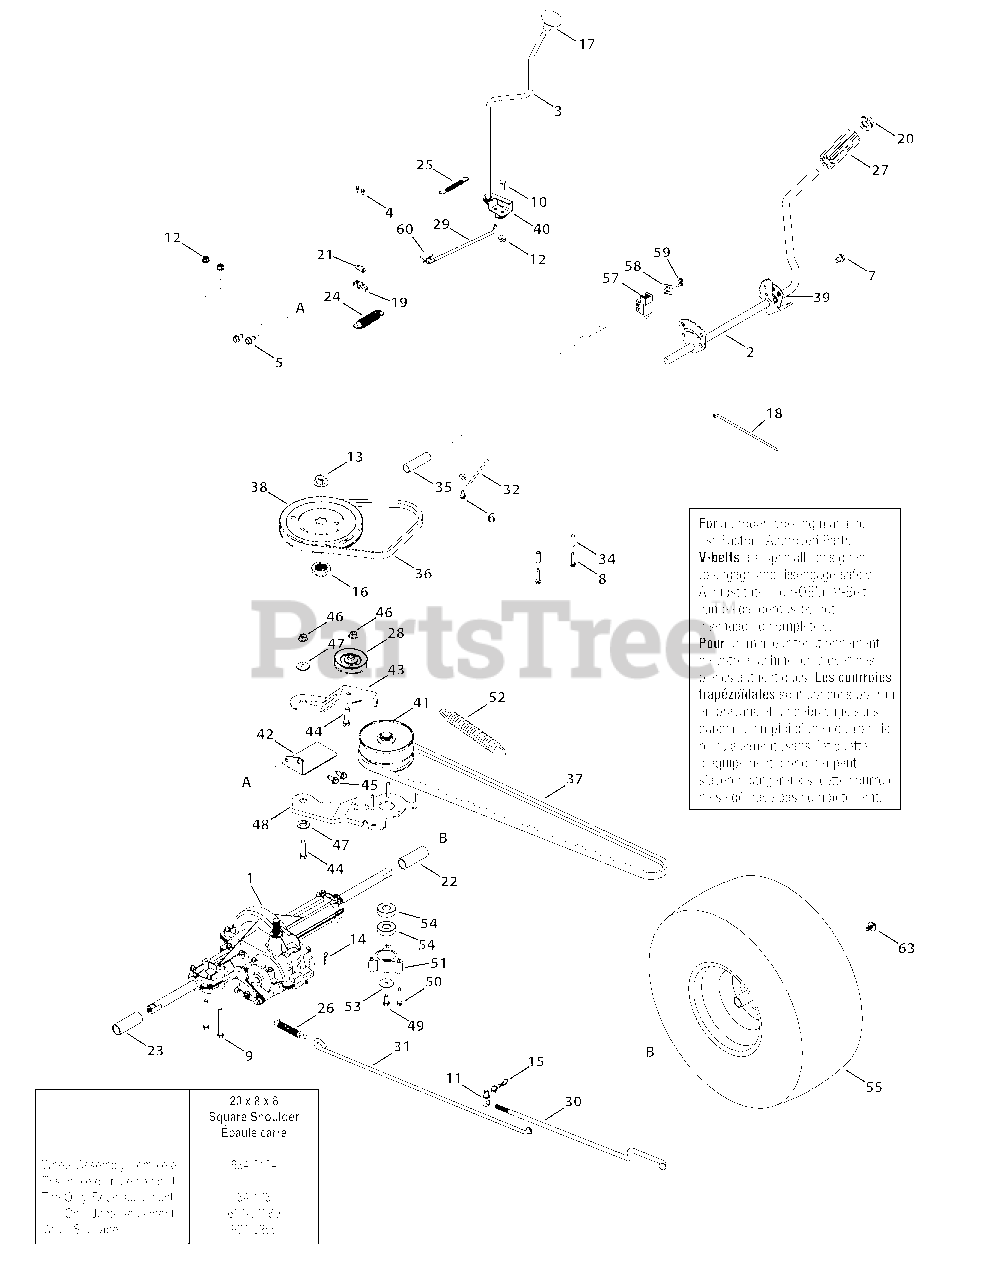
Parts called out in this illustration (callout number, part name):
1	Transmission Ass’y
2	Drive Pedal Assembly
3	Shift Lever Ass’y
4	Hex Wash HD AB S-Tapp Scr #8-.50
5	S-Tapp Scr 5/16-18 x .75
6	Hex Wash S-Tapp Scr 1/4-20 x .50
7	Self-tapping Screw 5/16-18 x .625
8	Hex Bolt 1/4-20 x 1.25
9	Hex Scr 5/16-18 x 2.75
10	Hex Bolt 5/16-18 x .75" Lg. Gr. 5
11	Ferrule
12	Flange Locknut 5/16-18 Gr. F, Nylon
13	Flange Nut
14	Cotter Pin
15	Bow Tie Cotter Pin
16	Pulley Hub 5/8" Spline
17	Shift Knob
18	Cable Tie
19	Short Spring Switch
20	Push Cap 5/8" Dia Rod
21	Insulator Nut Plate
22	Sleeve, .758 x .821 x 3.3125
23	Sleeve, .758 x .821 x 2.4375
24	Spring, Extension, .80 OD x 3.28
25	Spring, Extension
26	Ext. Spring .59 OD x 4.00 Lg.
27	Foot Pad
28	Flat Idler
29	Shift Rod (38"/42")
29	Shift Rod (46")
30	Control Rod, Variable Speed
31	Brake Rod
32	Belt Keeper Rod
34	Spacer .260 x .375 x 1.030 Lg.
35	Spacer .630 ID
36	Belt
38	Pulley, V-Type, 7.25 dia.
39	Pedal Support Bracket
40	Shift Bracket, Adjustable
41	Variable Speed Pulley Ass’y 4.75 OD
42	Transmission Torque Bracket
43	Idler Bracket
44	Screw, 3/8-16 x 1.75
45	Hex Wash. Hd. Scr. 5/16-18 x .75 Lg.
46	Flange Lock-Nut 3/8-16 Gr. F Nylon
47	Shoulder Spacer
48	Variable Speed Bracket Ass’y
49	Sems Screw 5/16-24 x 0.75 Gr. 5
50	Hex Scrw 1/4-20 x 1.5
51	Bearing Cup
52	Spring, Extension, .94 OD x 6.75
53	Flat Washer .22 ID x 1.25
54	Ball Bearing 17 x 40 x 12
55	Wheel Assembly Complete
55	Tire Only
55	Valve
57	Interlock Switch
58	Switch Plate
59	Shoulder Screw #10-32 x .5
60	Shift Plate Bearing
